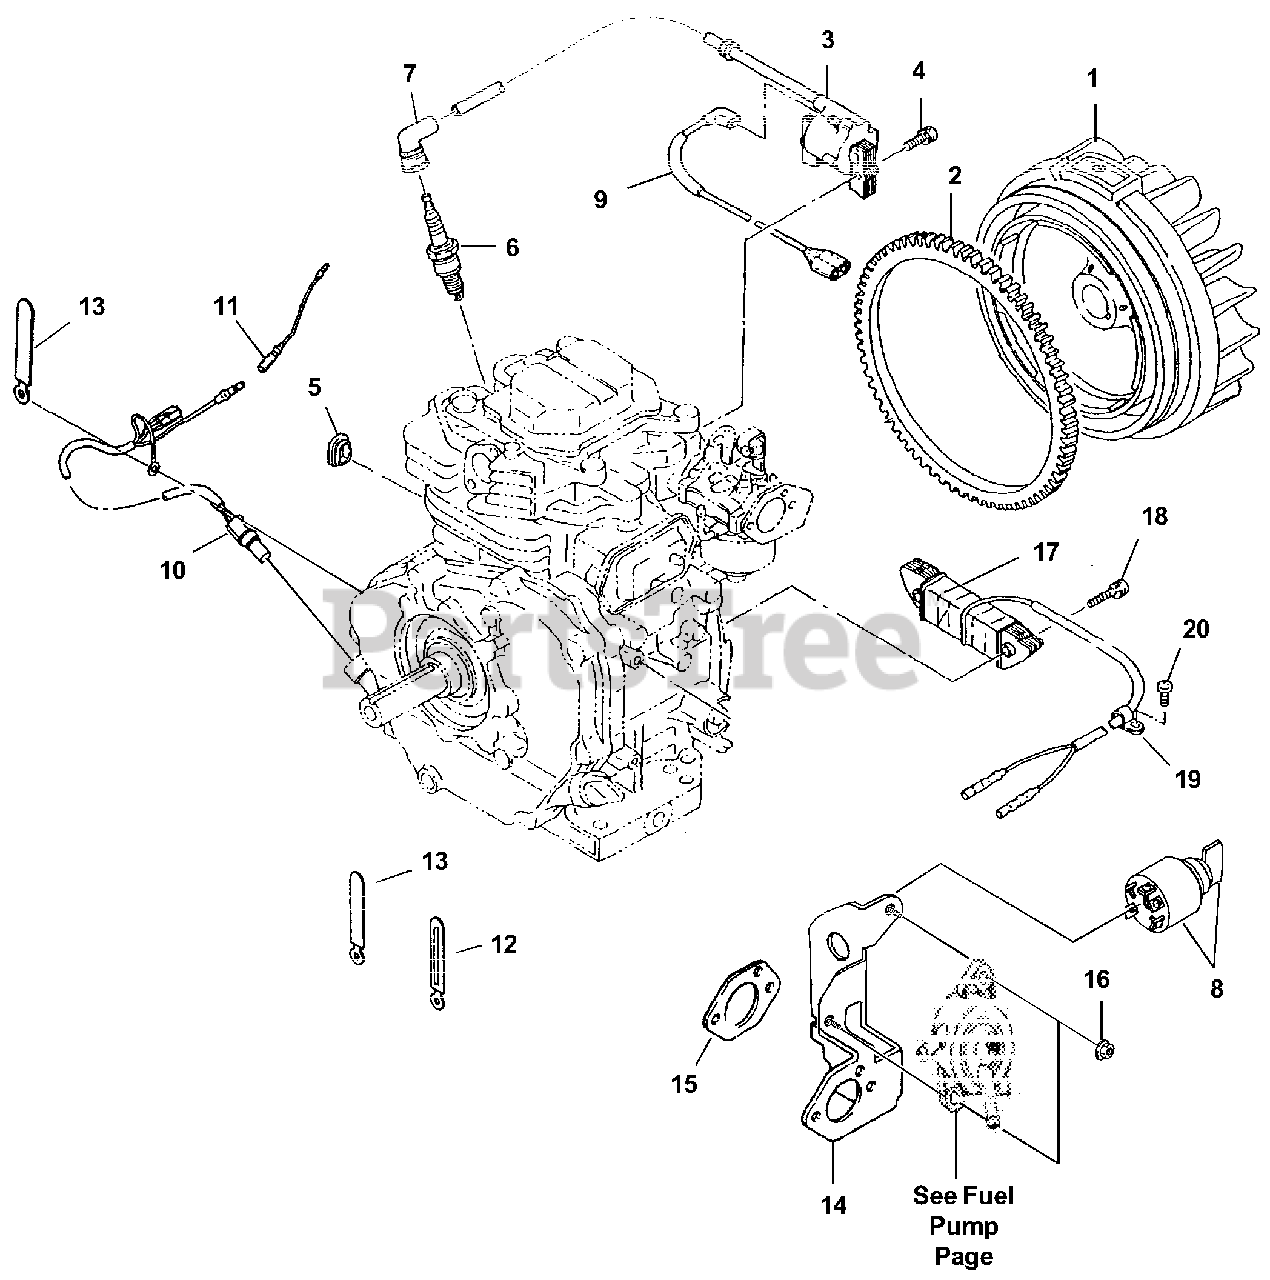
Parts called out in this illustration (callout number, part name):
1	Flywheel
2	Ring Gear
3	Ignition coil cp
4	Bolt and washer Ay
5	Grommet
6	Spark plug
7	Spark plug cap
8	Switch AY
9	Wire 3 cp
10	Oil Sensor cp
11	Wire 18 cp
12	Clamp cp
13	Clamp
14	Bracket, Fuel Pump
15	Gasket, Air Cleaner
16	Nut
17	Charging Coil
18	Screw & Washer AY
19	Clamp
20	Screw
